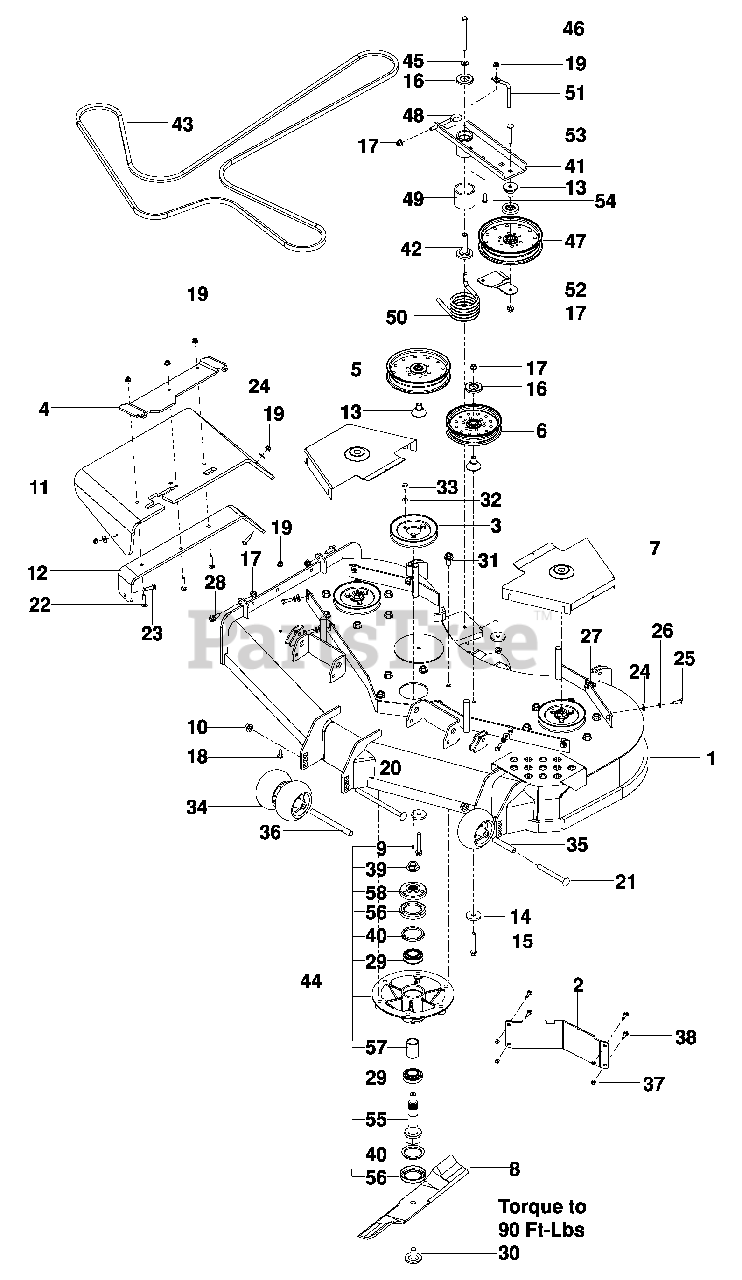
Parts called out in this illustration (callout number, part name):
1	DECK w/ SAFETY DECALS
2	BAFFLE, FLOW DIVERTER
4	BRACKET, CHUTE PIVOT
5	PULLEY, IDLER 7" NARROW
6	PULLEY, IDLER 6"
7	SHIELD, BELT
8	BLADE, 19"
9	ZERK
10	NUT ½-13 HEX FLG NYLOC
11	CHUTE, DISCHARGE
12	BRACKET, CHUTE SUPPORT
13	BEARING, IDLER ARM
14	WASHER, HEAVY
15	SCREW 3/8-16 x 2¾ HEX FLG
16	SHIELD, DUST
17	NUT 3/8-16 HEX FLG NYLOC
18	SCREW 5/16-18 x ¾ HEX FLG
19	NUT 5/16-18 HEX FLG NYLOC
20	BOLT ½-13 x 8 RD HD
21	BOLT ½-13 x 4¾ RD HD
22	BOLT 5/16-18 x 1½ RD HD
23	BOLT 5/16-18 x 1¼ RD HD
24	WASHER 5/16 STD FLT
25	BOLT 5/16-18 x 1 HEX HD
26	WASHER 5/16 SLW
27	RETAINER, U TYPE
28	SCREW 3/8-16 x 1 HEX FLG
30	BLADE BOLT
31	SCREW ½-13 x 1 HEX FLG
32	WASHER 5/16 DISC SPRING
33	BOLT 5/16-18 x ½ HEX NYLOC
34	ROLLER, GAUGE
35	TUBE, ROLLER AXLE
36	TUBE, ROLLER AXLE LONG
37	NUT ¼-20 HEX NYLOC
38	BOLT ¼-20 x 1 RD HD
39	NUT ¾-16 FLG
41	ARM, IDLER w/ BRGS, SPACR
42	BEARING, IDLER PIVOT
43	BELT, DECK
44	SPINDLE ASSY
45	WASHER 3/8 THICK
46	BOLT 3/8-16 x 4½ HEX GR 8
47	PULLEY, IDLER 7" WIDE
48	EYEBOLT 3/8 x 4
49	SPACER, IDLER PIVOT
50	SPRING, TORSION
51	KEEPER, BELT
52	GUIDE, BELT
53	BOLT 3/8-16 x 2½ CARRIAGE
54	BOLT 5/16-18 x 1 RD HD
55	SHAFT, SPINDLE
56	CUP, DEBRIS
